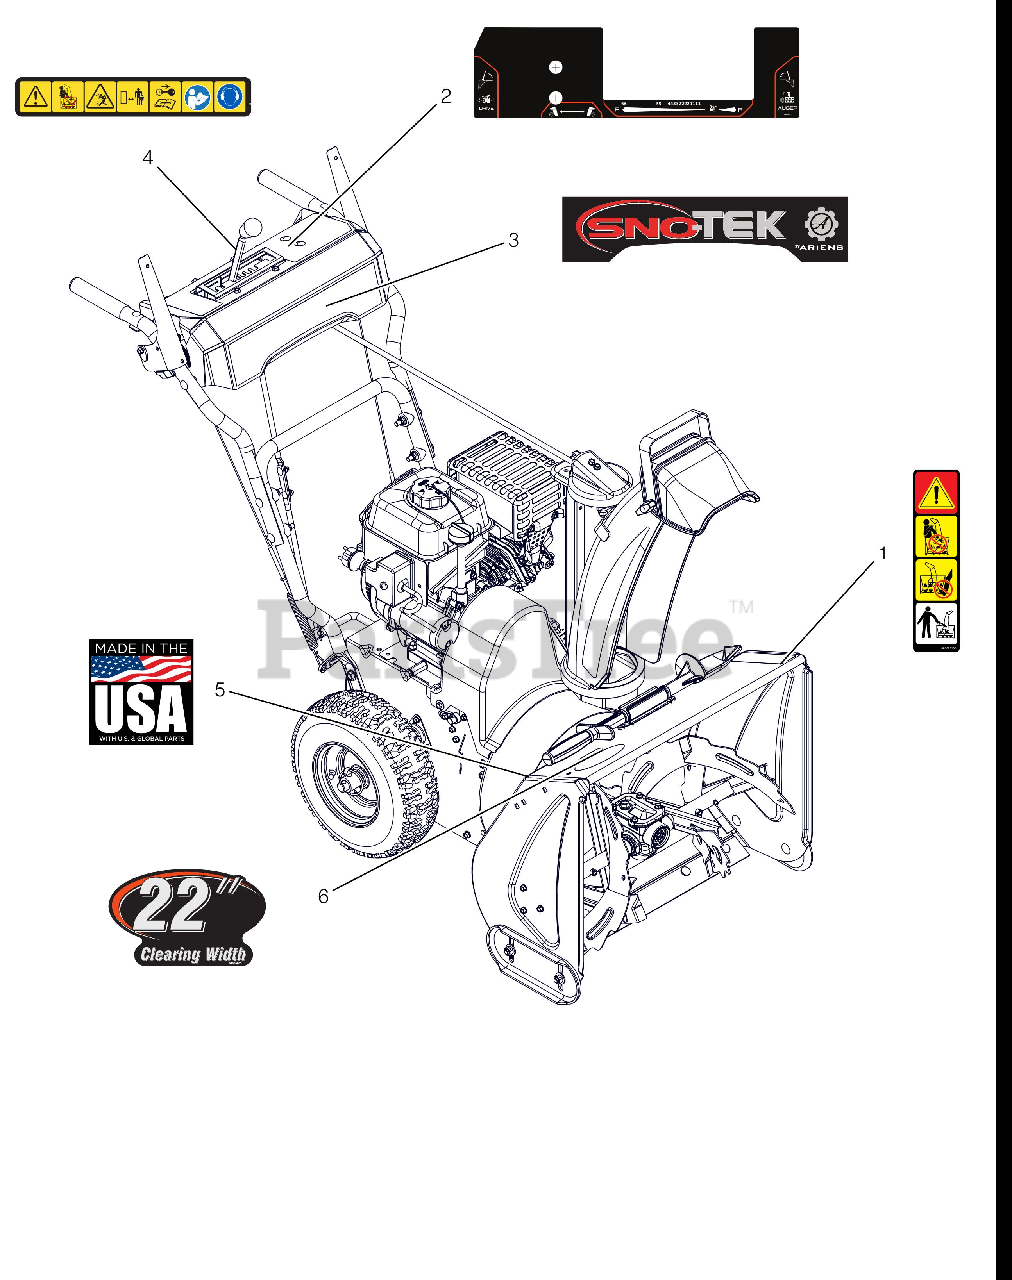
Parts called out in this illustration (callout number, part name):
1	DECAL, DANGER - ROTATING PARTS
2	DECAL,CONTROL-COMP MAN
3	DECAL, DASH, SNO-TEK
4	DECAL,DASH - SAFETY
5	DECAL, MADE IN USA
6	DECAL, HOUSING SNO-TEK 22
